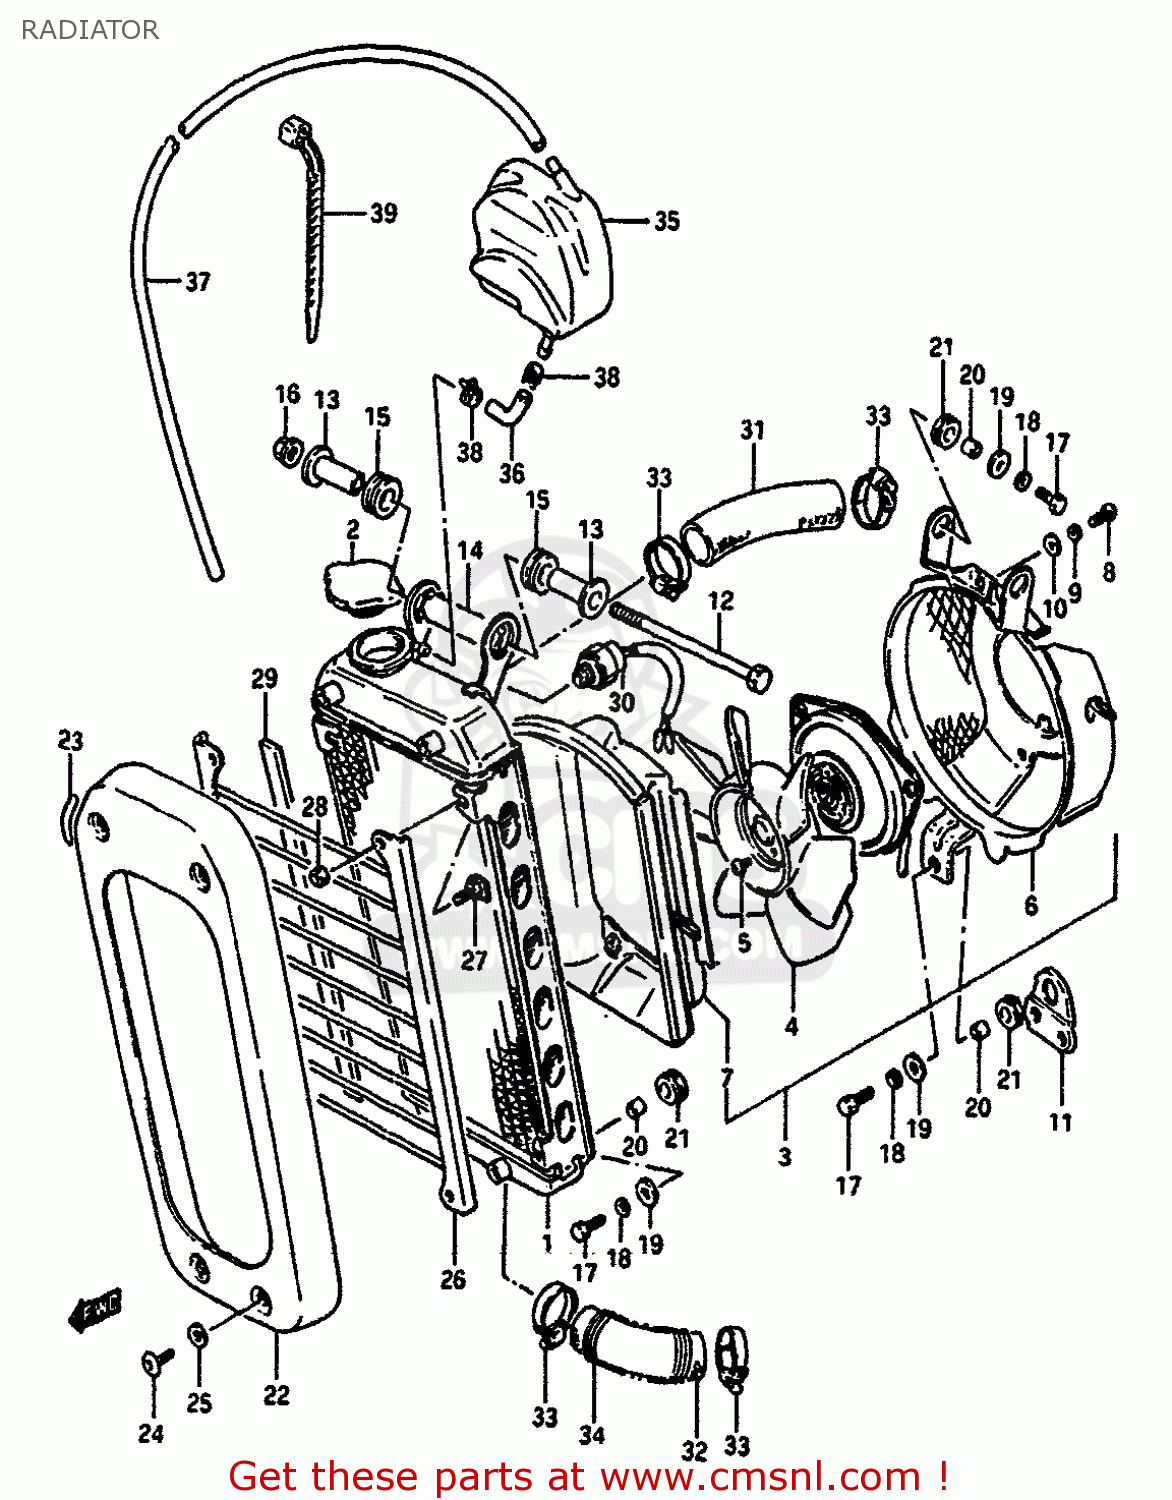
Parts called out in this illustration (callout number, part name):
1	RADIATOR COMP,WATER
2	CAP,RADIATOR
3	FAN ASSEMBLY,RADIATOR
4	FAN
5	BOLT
6	SHROUD,FAN
7	DUCT,FAN
8	SCREW 5X10
9	LOCK WASHER
10	WASHER
11	BRACKET,RADIATOR FAN
12	BOLT 10X135
13	SPACER,RADIATOR CUSHION
14	SPACER,RDTR CUSH NO.2 OUTER
15	CUSHION
16	NUT 10MM
17	BOLT 6X16
18	WASHER,LOCK
19	WASHER (6.5X18X1.6)
20	SPACER (6X9X8)
21	CUSHION
22	COVER,RADIATOR
23	TAPE,RATIATOR COVER
24	SCREW
25	WASHER (6.2X14X2)
26	BUMPER COMP,RADIATOR
27	BOLT
28	NUT 5MM
29	CUSHION,RADIATOR BUMPER
30	SWITCH
31	HOSE,RADIATOR INLET
32	HOSE,RADIATOR
33	CLAMP
34	SPRING
35	TANK,RESERVOIR
36	HOSE,RESERVE TANK INLET
37	HOSE,RESERVOIR TANK OVERFLOW
38	CLIP
39	CLAMP(L:125)
